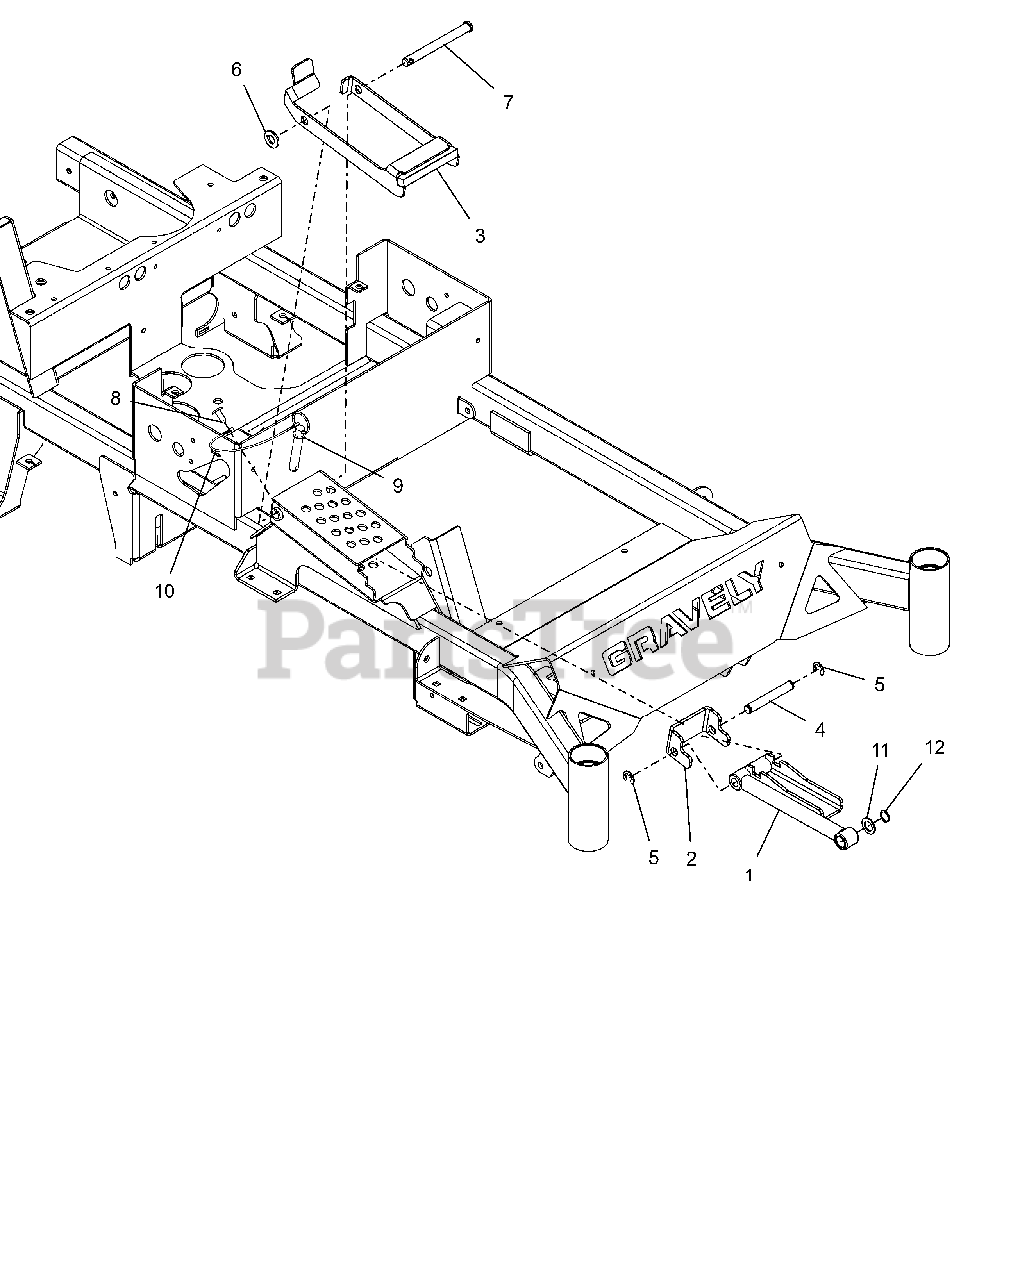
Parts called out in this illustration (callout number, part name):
1	WLDMT, COMAPCT HOC LIFT ARM
2	BRKT, COMPACT HOC LINE
3	WLDMT, TRANSFER LOCK
4	ROD, HOC PIVOT
5	RG-RTNG-EXT .500X.042 (E)
6	WSHR,FLT .531X1.062X.095 ZCC
7	PIN, SLIC-.500X4.97X4.55 -ZC
8	XMAS TREE FASTNER-BLACK
9	PIN, .50 X 2.20 USABLE LG BALL
10	CABLE, 12.0 LANYARD, NYLON
11	WSHR, FLT .630X1.005X.062 ZCC
12	RG-RTNG-EXT .579X.035
